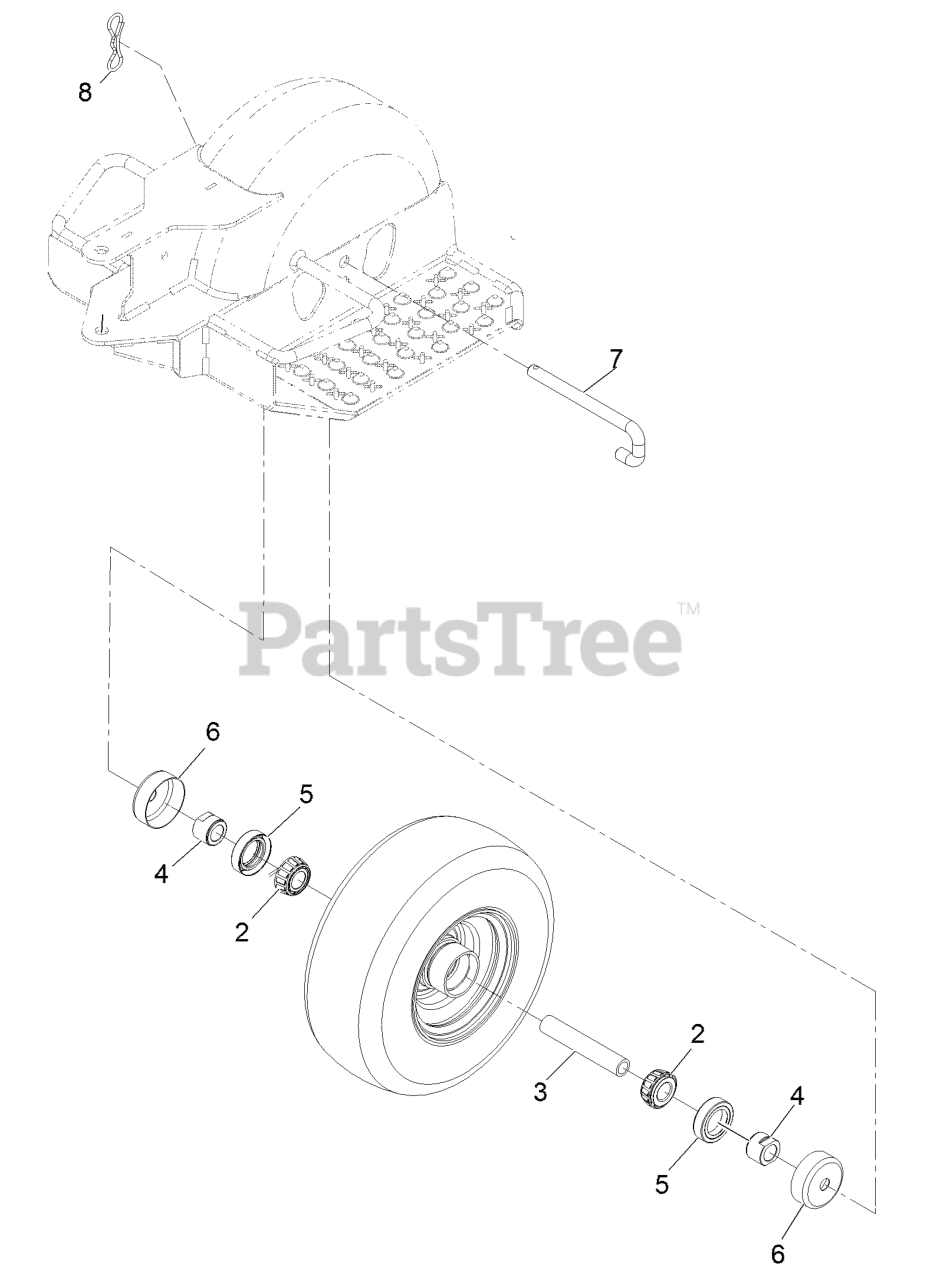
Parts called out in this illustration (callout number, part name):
2	BEARING-CONE, TAPERED ROLLER
4	SPACER-NUT
5	SEAL-CASTER
6	GUARD-SEAL
7	PIN, CASTER
8	PIN-COTTER, LOCKING
